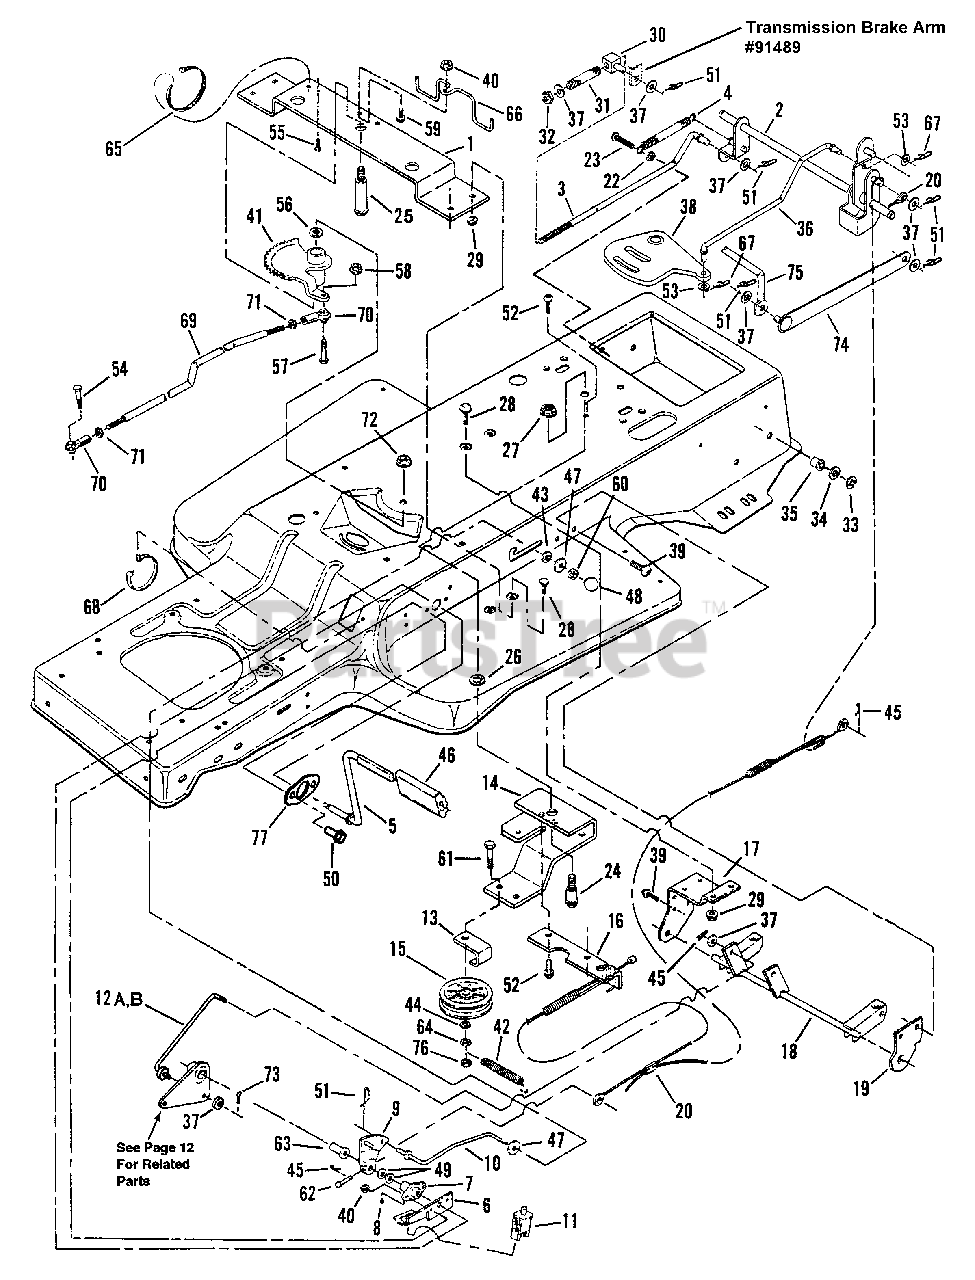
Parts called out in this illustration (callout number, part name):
1	BRACE, Sector Gear
2	WELDMENT, Brake Arm
3	ROD, Brake
4	SPRING
5	PEDAL, Park Brake
6	BRACKET, Brake Switch
7	ASSEMBLY, Foot Shaft Pivot
8	FITTING, 3/16 Lube
9	ASSEMBLY, Clutch/Brake Arm
10	LATCH, Park Brake
11	SWITCH (NC/NO)
12A	ROD, Lift Link
12B	ROD, Lift Link
13	GUIDE, Pulley
14	ARM, Idler (Traction Drive)
15	PULLEY
16	EXTENSION, Idler Arm
17	BRACKET, Rear Lift/PTO Lever
18	WELDMENT, Rear Lift
19	BRACKET, Deck Hang Pivot
20	ASSEMBLY, Clutch/Brake Cable
22	NUT, 5/16-18 Hex Center Lock
23	SCREW, 5/16-18 x 1-1/4" Self-Tapping
24	BOLT, 1/2-13 x 2" Shoulder
25	BOLT, 1/2-13 x 3-7/8" Shoulder
26	WASHER, 1/2 Internal Lock
27	NUT, 1/2-13 Hex Flange Lock
28	BOLT, 1/4-20 x 5/8" Carriage
29	NUT, 1/4-20 Flange Lock
30	SWIVEL, Inline Brake
31	SPRING, Brake
32	NUT, 3/8-16 Hex Nyloc
33	RING, 1/2" Ext. Retaining
34	WASHER, 1/2 Flat
35	BEARING, Nylon
36	LINK, Speed
37	WASHER, 3/8" Flat
38	ARM, Trans. Speed Control
39	SCREW,5/16-18x5/8" Truss Head (Torx)
40	NUT, 5/16-18 Hex Fla. Lock
41	ASSEMBLY, Sector Gear
42	SPRING, Idler
43	RETAINER, 5/16 Bolt
44	WASHER, 3/8 Split Lock
45	PIN, 3/32 x 1-1/2" Hair
46	PAD, Pedal
47	WASHER,5/16 Nylon
48	KNOB, Push/Pull
49	WASHER, 5/8 Flat
50	SCREW,5/16-18 x 7/8" Truss Head (Torx)
51	PIN, 3/64 x 1-7/32" Cotter (Self Locking)
52	SCREW, 5/16-18x 5/8" Self-Tapping
53	WASHER,5/16 Flat
54	SCREW, 3/8-24 x 1-1/4" Hex Head Cap
55	SCREW, #10-24 x 1/2" Hex Washer Self-Tap (Torx)
56	WASHER, 3/4 Thrust
57	SCREW, 3/8-16 x 1-1/2" Hex Head Cap
58	NUT, 3/8-16 Hex Flange Lock
59	BOLT, 5/16-18 x 3/4" Hex Flange Lock
60	RING, Tolerance
61	SCREW, 3/8-16 x 2-1/4" Hex Head Cap
62	PlN, 3/16 x 1-1/2" Clevis
63	BEARING, Flange
64	NUT, 3/8-16 Hex Nut
65	TIE, Cable
66	GUIDE, Drive Belt
67	PIN, 5/16 Cotter (Self-Locking)
68	TIE, Wire
69	ASSEMBLY, Drag Link
69	LINK, Drag
70	BALL JOINT, 3/8-24
71	NUT, 3/8-24 Hex Jam
72	NUT, 1/2-13 Hex Center Lock
73	PIN, 3/32 x 3/4" Cotter
74	LINK, Shift
75	ASSEMBLY, Shift Lever (Lower)
76	NUT, 3/8-16 Hex Center Lock
77	WASHER, Pivot- Stiffener
